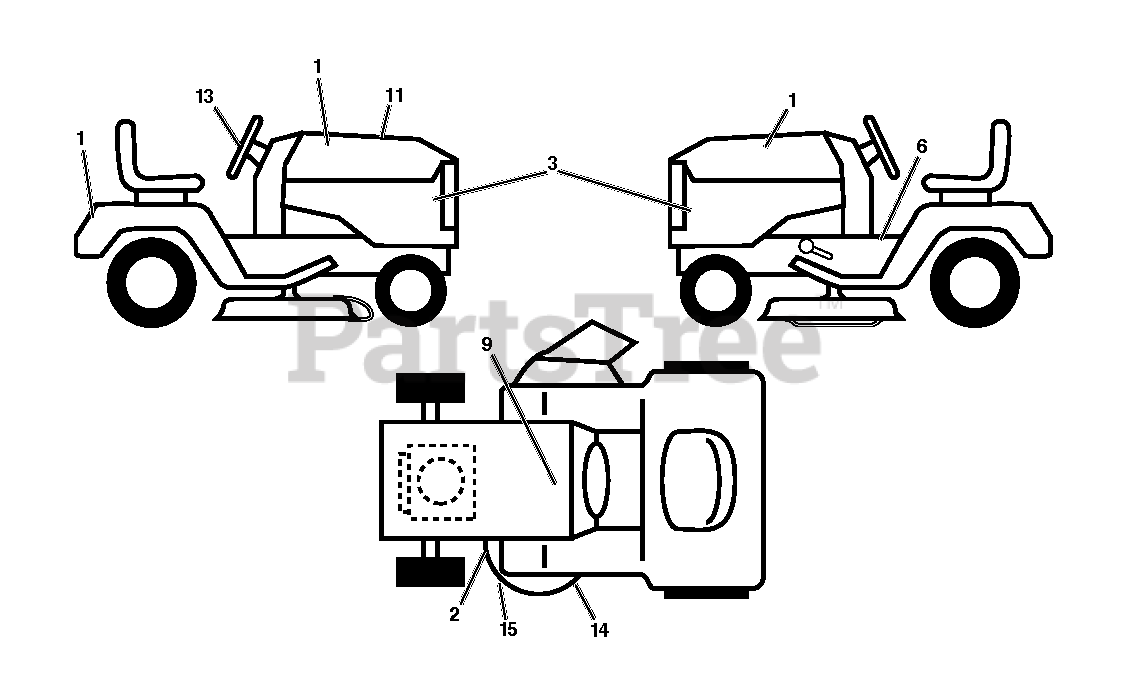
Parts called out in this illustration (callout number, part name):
2	DECAL
9	DECAL BTRY SYMBOLS
11	DECAL.RPL
14	DECAL.MOWER.SCH.48/54
15	DECAL.MOWER
